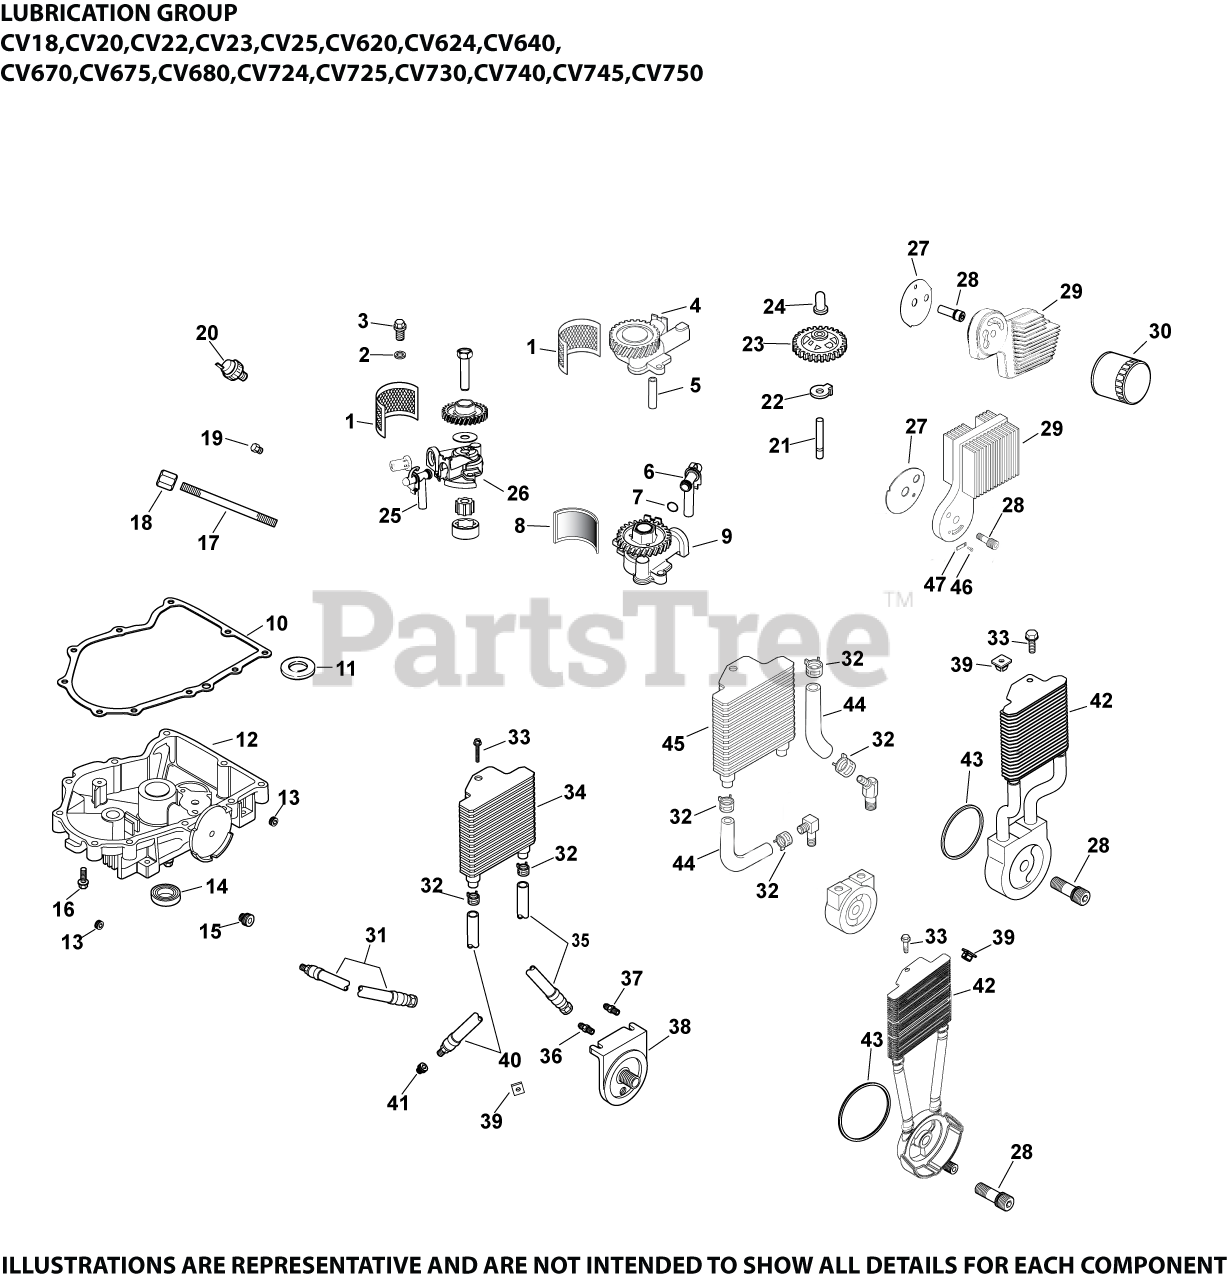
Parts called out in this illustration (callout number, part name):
6	KIT, OIL PICK-UP TUBE
7	O-RING, OIL PICK-UP
8	SCREEN, OIL
9	KIT, OIL PUMP ASSEMBLY
10	GASKET, OIL PAN
12	KIT, OIL PAN USE 24 199 35-S
13	PLUG, PIPE CTSK 3/8"
14	SEAL, OIL
16	SCREW, FLG M8X1.25X45
21	SHAFT, GOVERNOR GEAR
22	TAB, LOCKING
23	KIT, GOVERNOR GEAR W/PIN
24	PIN, GOVERNOR REGULATING
28	NIPPLE, OIL FILTER
30	OIL FILTER
39	NUT, PLASTIC - BLACK
42	KIT, OIL COOLER
43	O-RING, OIL COOLER
